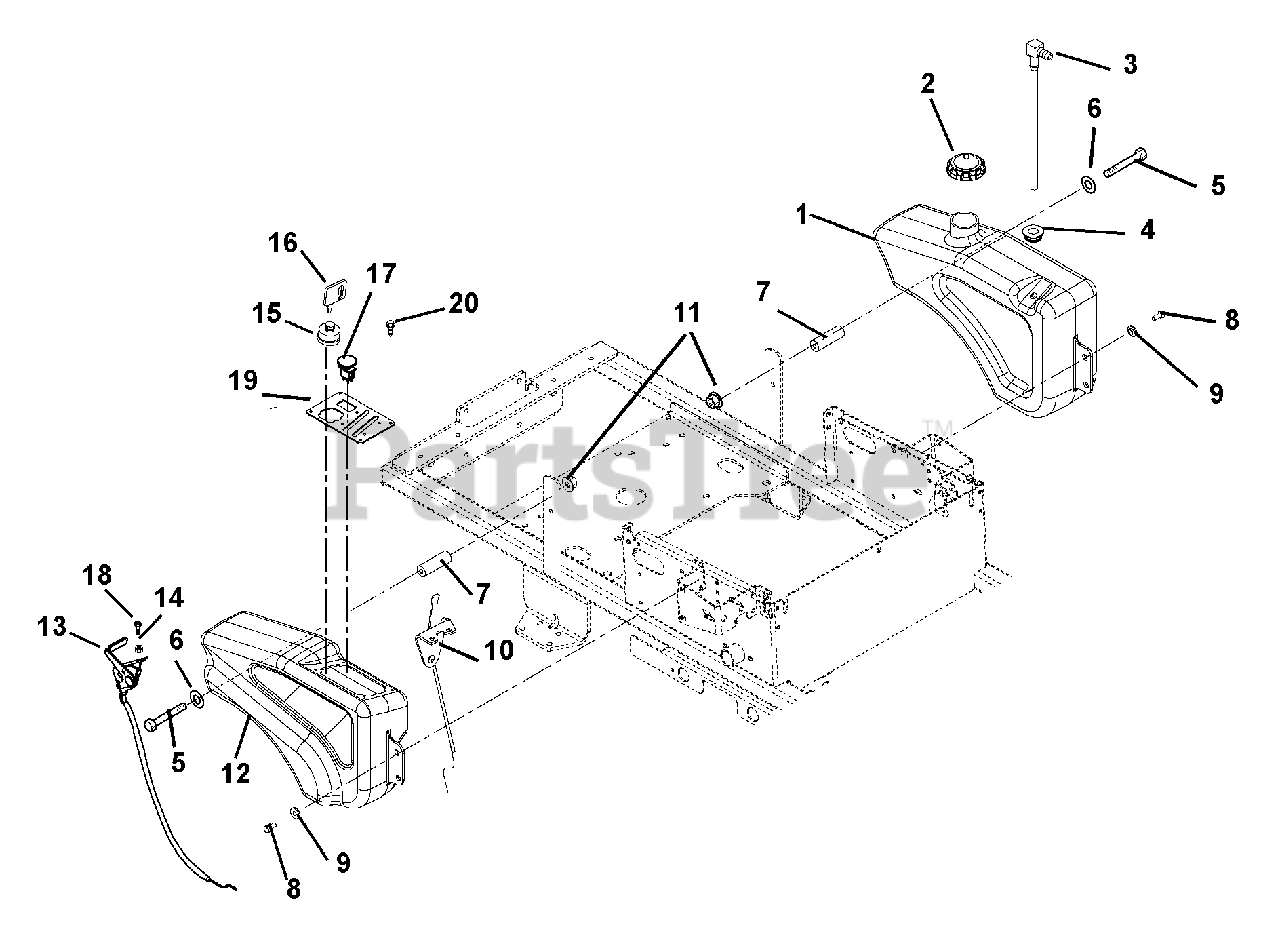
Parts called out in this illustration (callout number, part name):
1	GAS TANK, ZOOM
2	FUEL CAP
3	FITTING, TANK
4	BSHG-FLG .375 X 1.062 X .625 R
5	@BLT-HEX .31-18X3.50 GR5 YWZC
6	@WSHR-FL-STL.38X.875X.083 YWZC
7	SPCR, FLG .32X.49X.15X2.64
8	@BLT-HEX .31-18X.75 GR5 YWZC
9	BSHG, FLG .325X.499X.26X.88
10	CABLE, CHOKE CABLE
11	@NUT-LK-NYL-FLG .31-18 YWZC
12	FENDER, ZOOM
13	CABLE, ZOOM THROTTLE
14	@NUT-LK-NYL 10-24 W/INSRT YWZC
15	KEY SWITCH
16	KEY -W/CAP
17	SWITCH, CLUTCH
18	@SCR-MCH 10-24X.75 HWH YWZC
19	PANEL, ZOOM CONTROL
20	RIVET, PLASTIC .195 DIA.
